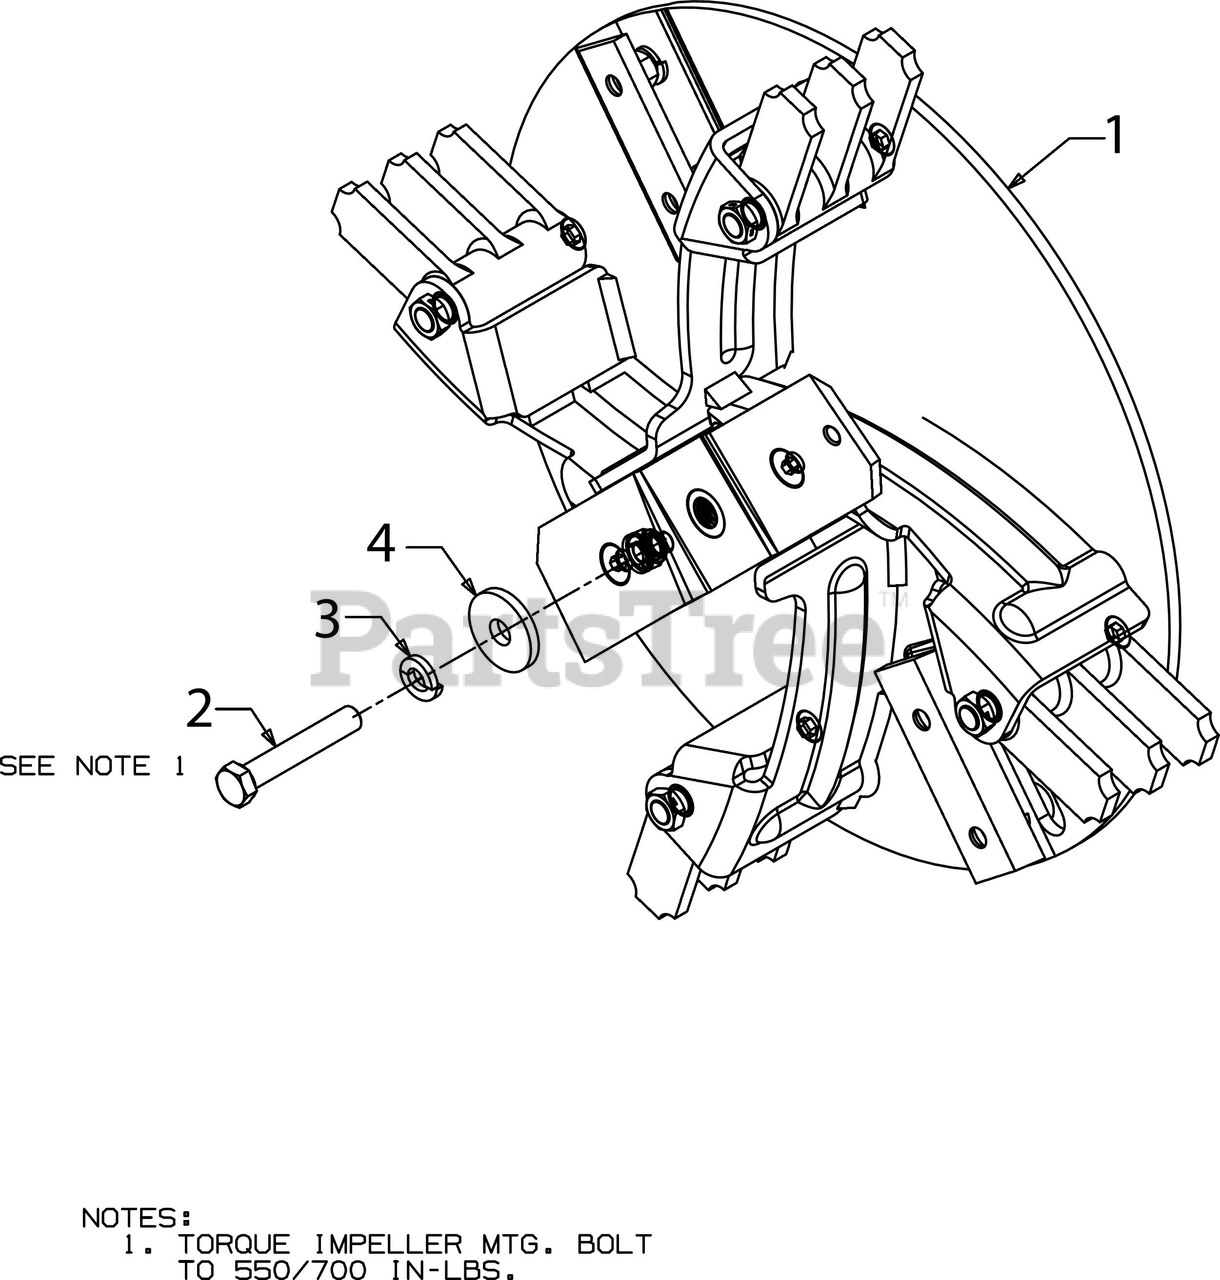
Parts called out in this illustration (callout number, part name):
1	IMPELLER ASSEMBLY
2	SCREW 3/8-24X2.25 GR8
3	LOCK WASHER 3/8HD
4	FLAT WASHER
